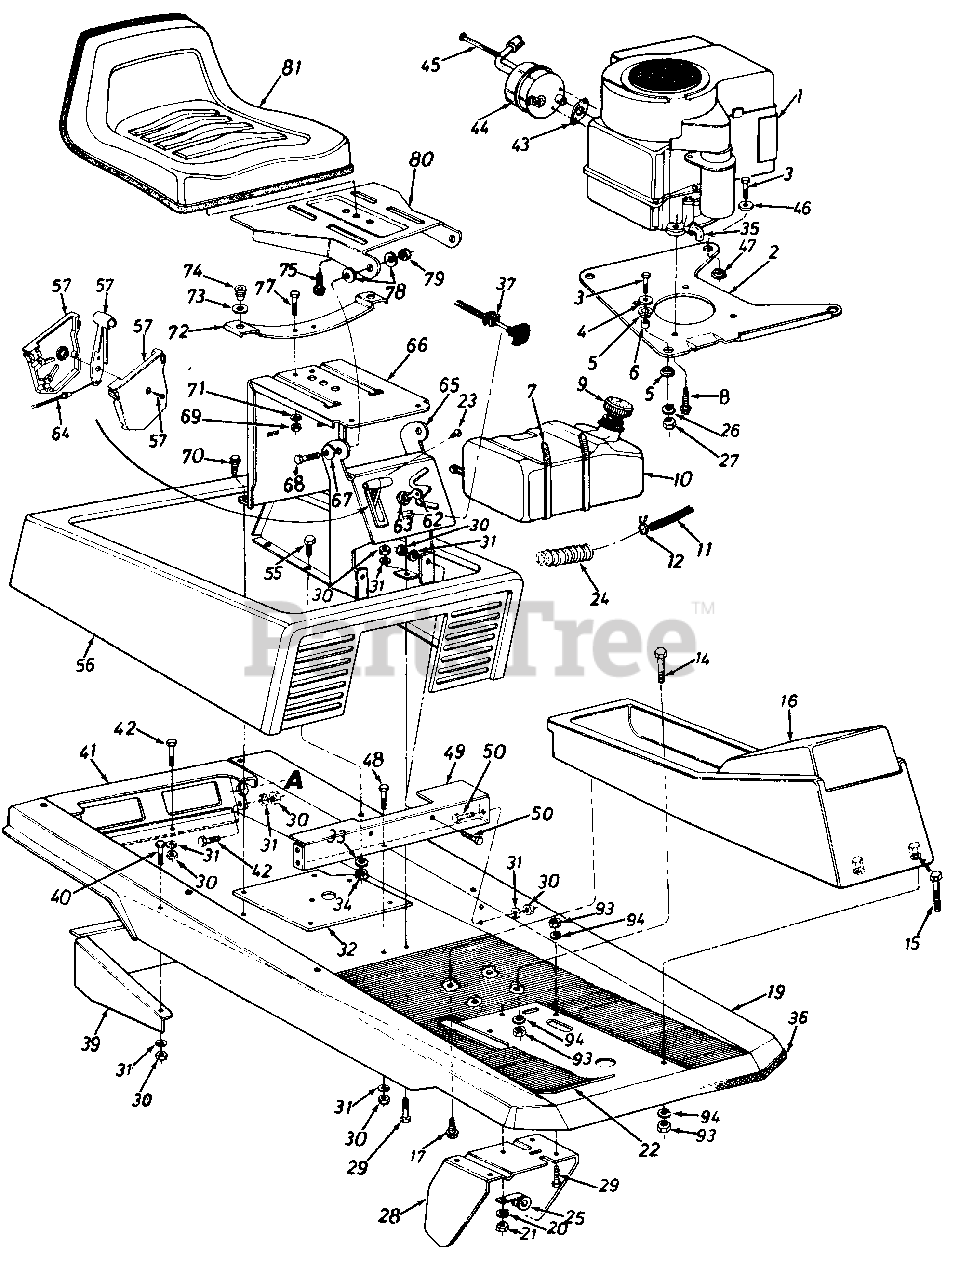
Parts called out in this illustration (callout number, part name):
1	Engine
2	Engine Mounting Plate
3	Hex Bolt 5/16-24 x 1.25" Lg.
4	Fl-Wash. .330" I.D. x 1.125 O.D.
5	Engine Mounting Grommet
6	Spacer .315" I.D. x .50" O.D. x.520" Lg.
7	Cable Tie 30.6 Lg.
8	Hex Wash. Hd. Self-Tap Scr. 3/8-16 x 1.25" Lg.
10	Fuel Tank
11	Gas Line
12	Hose Clamp-.406" Dia.
14	Hex Bolt 5/16-18 x 1.75" Lg.
15	Hex Bolt 5/16-18 x 2.0" Lg.
16	Front Console
17	Plastite Scr. 5/8 x 1.25"
19	Main Frame
20	L-Wash. 5/16" I.D.
21	Hex Nut 5/16-18 Thd.
23	Truss Mach. AB-Tap Scr. #10 x .50" Lg.
24	Convoluted Conduit
26	L-Wash. 5/16" I.D.
27	Hex Nut 5/16-24 Thd.
28	Clutch-Brake Podal Ass'y.
29	Hex Bolt 5/16-18 x .75" Lg
30	Hex Nut 5/16-18 Thd.
31	L-Wash. 5/16" I.D.
32	Mounting Brkt. Variable Speed Pulley
33	L-Wash. 1/4" I.D.
34	Hex Nut 1/4-20 Thd.
35	90ø Elbow Male To Female
36	Trim Strip 18" Lg.
37	Choke Control
39	Transaxle suppon Ass'y.
40	Hex Bolt 5/16-18 x .75" Lg.
43	Exhaust Gasket
44	Muffler Ass'y.
45	Shld. Bolt
46	Fl-Wash. .33" I.D. x 1.25" O.D.
47	Flange Wash. 32n l.D. x .75" O.D.
49	Seat Support & Frame Brkt.
50	Hex Bolt 5/16-18 x .75" Lg.
55	Hex Bolt 1/4-20 x .50" Lg.
56	Engine Cover Ass'y.
57	Throttle Control Box Ass'y.
62	Ignition Key
63	Ignition Switch
64	Throttle Control Wire
65	Front Seat Bracket
66	Rear Seat Bracket
67	Bell-Wash. .345" I.D. x .88" O.D.
68	Hex Bolt 5/16-18 x .75" Lg.
69	Hex Nut 5/16-18 Thd.
70	Hex Selt-Tap Scr. 5/16-18 x .75" Lg.
71	L-Wash. 1/4" I.D.
72	Seat Spring
73	Fl-Wash. .531" I.D. x .930" O.D.
74	Grommet
75	Hex Wash. Hd. Tap Scr. 3/8-16 x 3/4" Lg.
77	Hex Bolt 1/4-20 x .75" Lg.
78	Bell-Wash. .345" I.D. x .88" O.D.
79	Hex Cent. L-Nut 5/16-18 Thd.
80	Seat Pivot Bracket
81	Seat Ass'y. Comp.
93	Hex Nut 5/16-18 Thd.
94	L-Wash. 5/16" I.D.
